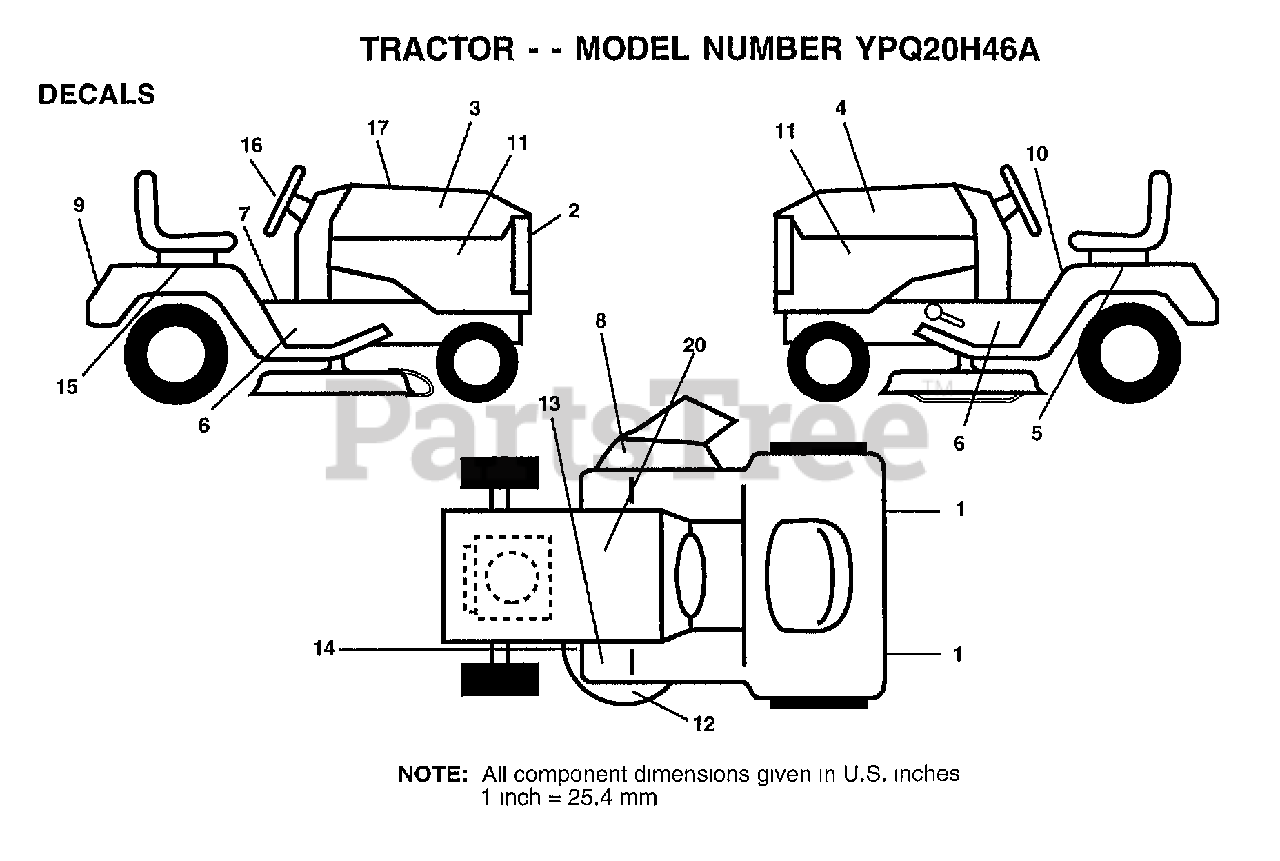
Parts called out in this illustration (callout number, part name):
1	REFLECTOR-TAIL YT
1	VALVE CAP
2	VALVE STEM LT
3	DECAL.HOOD.RH
4	DECAL.HOOD.LH
4	TUBE.5.3/4.5/6
5	DECAL FENDER RH
5	"RIM ASM 6"" FRT"
6	"DECAL-CHASSIS,46"""
6	FITTING LT
7	DECAL SADDLE OPER
7	"FLANGE, BEARING"
8	"DECAL, WARNING"
8	"RIM AS 8"" REAR"
9	DECAL FENDER
10	DECAL.CAUT.ENG/FR
10	TUBE.18X9.5-8
11	DECAL.DASH
11	HUB CAP
12	DECAL.MOWER
13	DECAL T
15	DECAL FENDER RH
16	DECAL INS STRG WH
17	DECAL HOOD REP PARTS
20	DECAL.BATRY.3-3908
